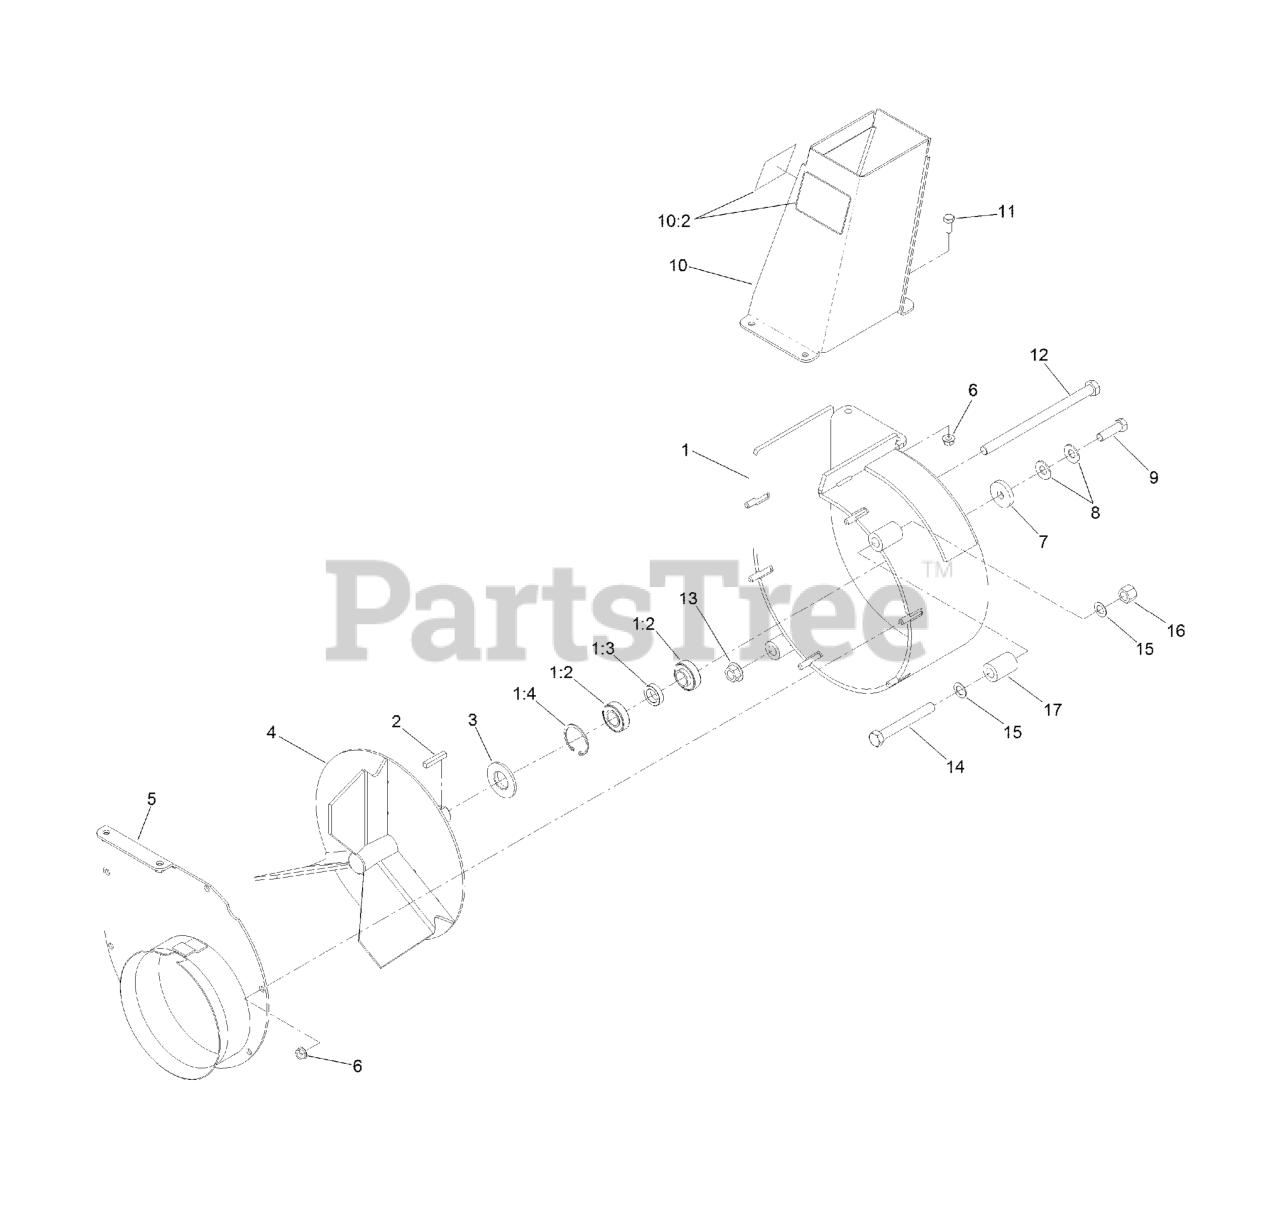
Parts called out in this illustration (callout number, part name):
1	HOUSING ASM
1:2	BEARING-BALL
1:3	SPACER-BEARING
1:4	RING-SNAP
2	KEY-SQUARE
3	SPACER-BLOWER
4	IMPELLER-3 BLADE
5	COVER-BLOWER
7	WASHER-CLUTCH
8	WASHER-SPRING
9	SCREW-HH
10	DISCHARGE CHUTE ASM
10:2	DECAL-DANGER, IMPELLER
11	SCREW-HH
12	SCREW-HH
14	SCREW-HH
15	WASHER-THRUST
16	NUT-LOCK, NI
17	SPACER-MOUNT
